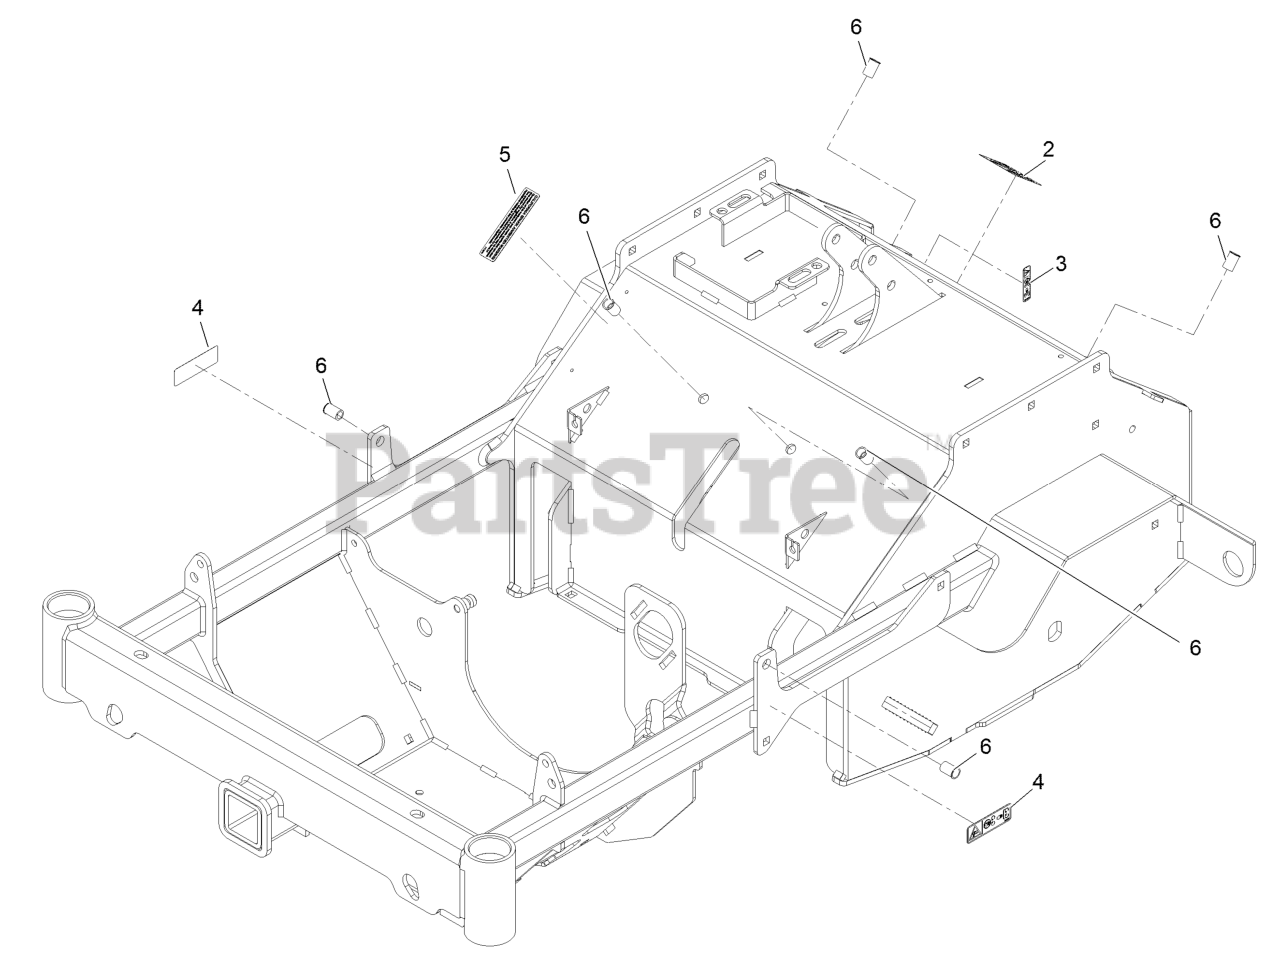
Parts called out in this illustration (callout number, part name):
2	Decal-Warning
3	Decal-Warning
4	Decal-Danger
5	Decal-Arrester, Spark
6	Insert-Nut
